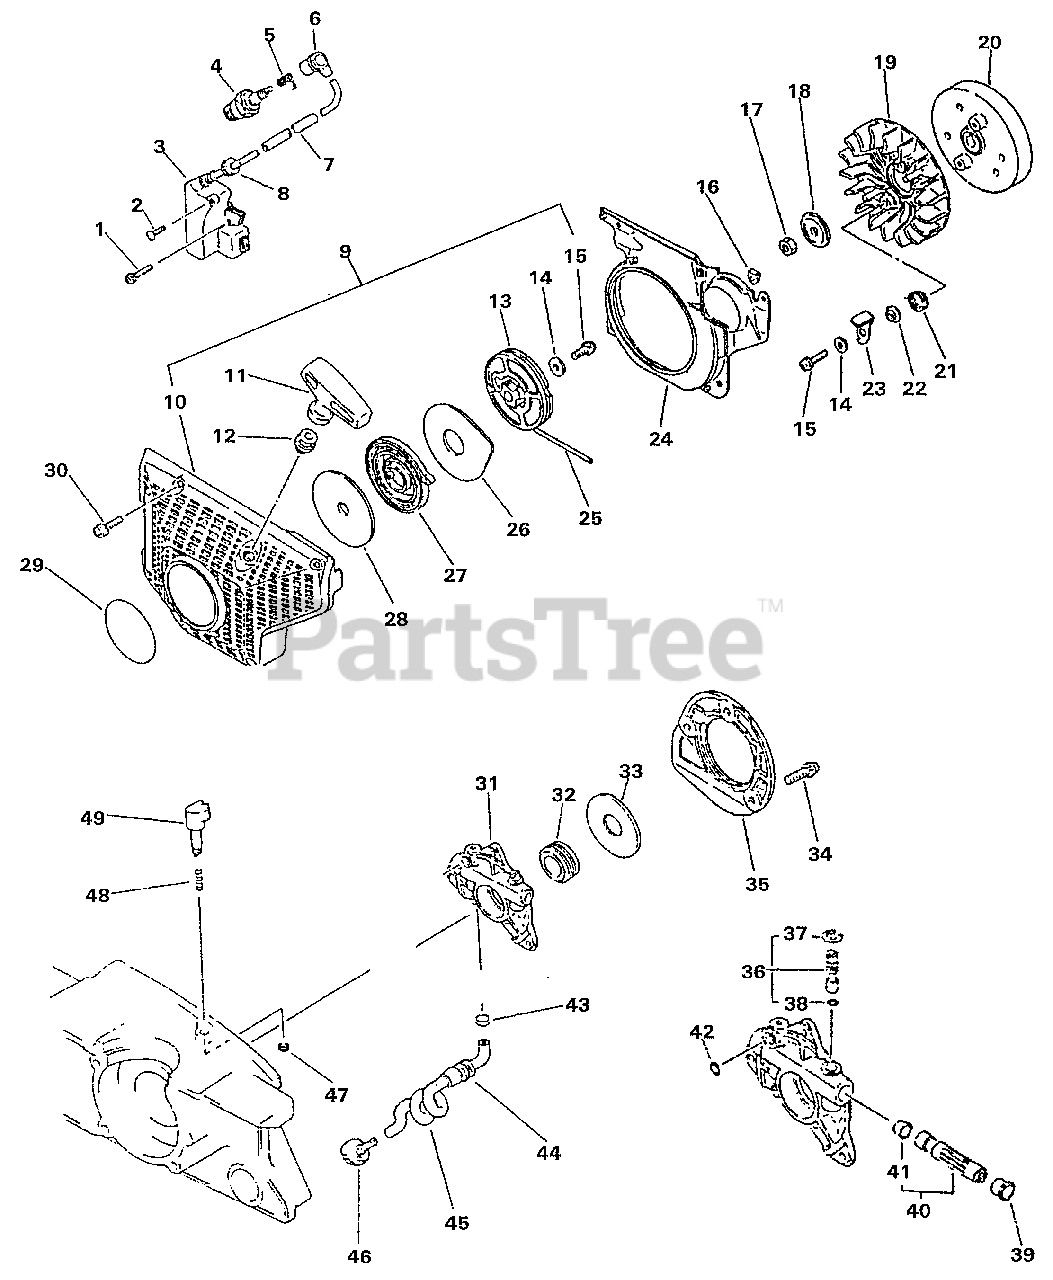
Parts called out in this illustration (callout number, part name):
1	SCREW - 4X20
2	SCREW - 4X8
3	COIL, IGNITION
4	SPARK PLUG -- BPM-7A
5	TERMINAL, SPARK PLUG CAP
6	CAP, SPARK PLUG
9	STARTER ASSY
10	CASE, STARTER
11	GRIP, STARTER
12	GUIDE, ROPE
13	REEL, ROPE
14	WASHER - 5
15	SCREW - 5X14
18	WASHER - CUP
20	FLYWHEEL
21	SPRING, RETURN
23	PAWL, STARTER
24	SHIELD, FAN
25	ROPE, STARTER - 3X850
26	PLATE, STARTER
27	SPRING, REWIND
28	PLATE, STARTER
29	SCREW - 5X18
30	LABEL - ECHO
31	AUTO-OILER ASSY
32	GEAR - WORM
33	WASHER - 12
34	SCREW - 4X12
35	COVER, OIL PUMP
36	CONTROL PIN ASSY
39	CAP, PLUNGER
40	PLUNGER KIT
42	O-RING - 3
43	CLIP - 6.5
45	PIPE, OIL - SPIRAL
46	FILTER, OIL
47	RING, RETAINING - 3
49	DIAL, AUTO-OILER
